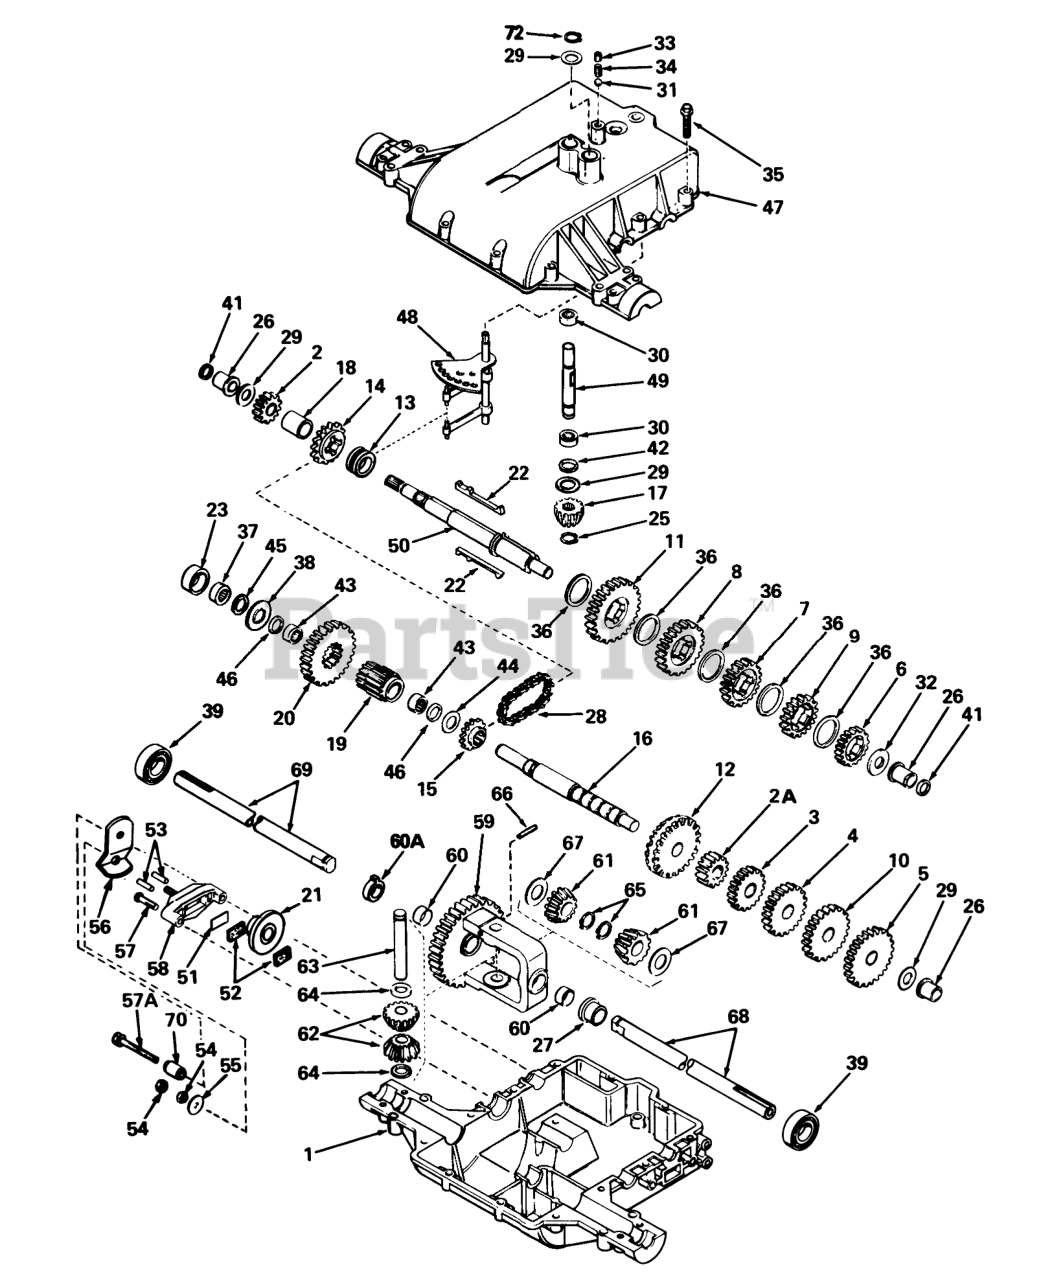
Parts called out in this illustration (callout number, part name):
1	Case-transaxle
2	Gear-Spur 15 Teeth
2A	Gear-Spur, 12 Teeth
3	Gear-Spur, 20 Teeth
4	Gear-Spur, 25 Teeth
5	Gear-Spur (30 teeth)
6	Gear-Spur 20 teeth
7	Gear-Spur, 25 Teeth
8	Gear-Spur, 30 Teeth
9	Gear-Spur (22 teeth)
10	Gear-Spur (28 teeth)
11	Gear-Spur, 37 Teeth
12	Gear-Bevel (42Teeth)
13	Collar-Shift
14	Sprocket-18 Teeth
15	Sprocket-9 Teeth
16	Shaft-Counter
17	Bevel Pinion-Input
18	Spacer
19	Pinion-Output
20	Gear-Output
23	Spacer
25	Ring-Retainer
26	Bushing-Flange
27	Bushing-Flanged
28	Chain-Roller #41
29	Washer
30	Bearing-Needle
31	Ball-Steel
32	Washer
33	Screw-Set
34	Spring
35	Ring Set (.020 O S)
36	Washer
37	Bearing-Needle
38	Washer-Flat
39	Bearing-Ball
41	Ring-Square Cut
42	O Ring
43	Bearing-Needle
44	Washer-Flat
45	Ring-Square Cut
46	Ring-Square Cut
47	Cover-Transaxle
48	Rod & Fork Assembly
49	Shaft-Input
50	Shaft-Brake
51	Brake Pad Plate
52	Brake Pad
53	Dowel Pin
54	Locknut
55	Washer
56	Lever-Brake
57	Ring Set (.020 O S)
57A	Screw-Hex. Flange
58	Holder-Brake Pad
59	Gear Assy., Differential (Incl. 2 of No. 60)
60	Bushing
60A	Bushing
61	Bevel Gear
62	Gear Pinion
63	Drive Pin
64	Thrust Washer
65	Ring-Snap
66	Pin-Roll
67	Washer
68	Axle (14-7/8" long)
69	Axle (13" long)
70	Spacer
72	Ring-Snap
